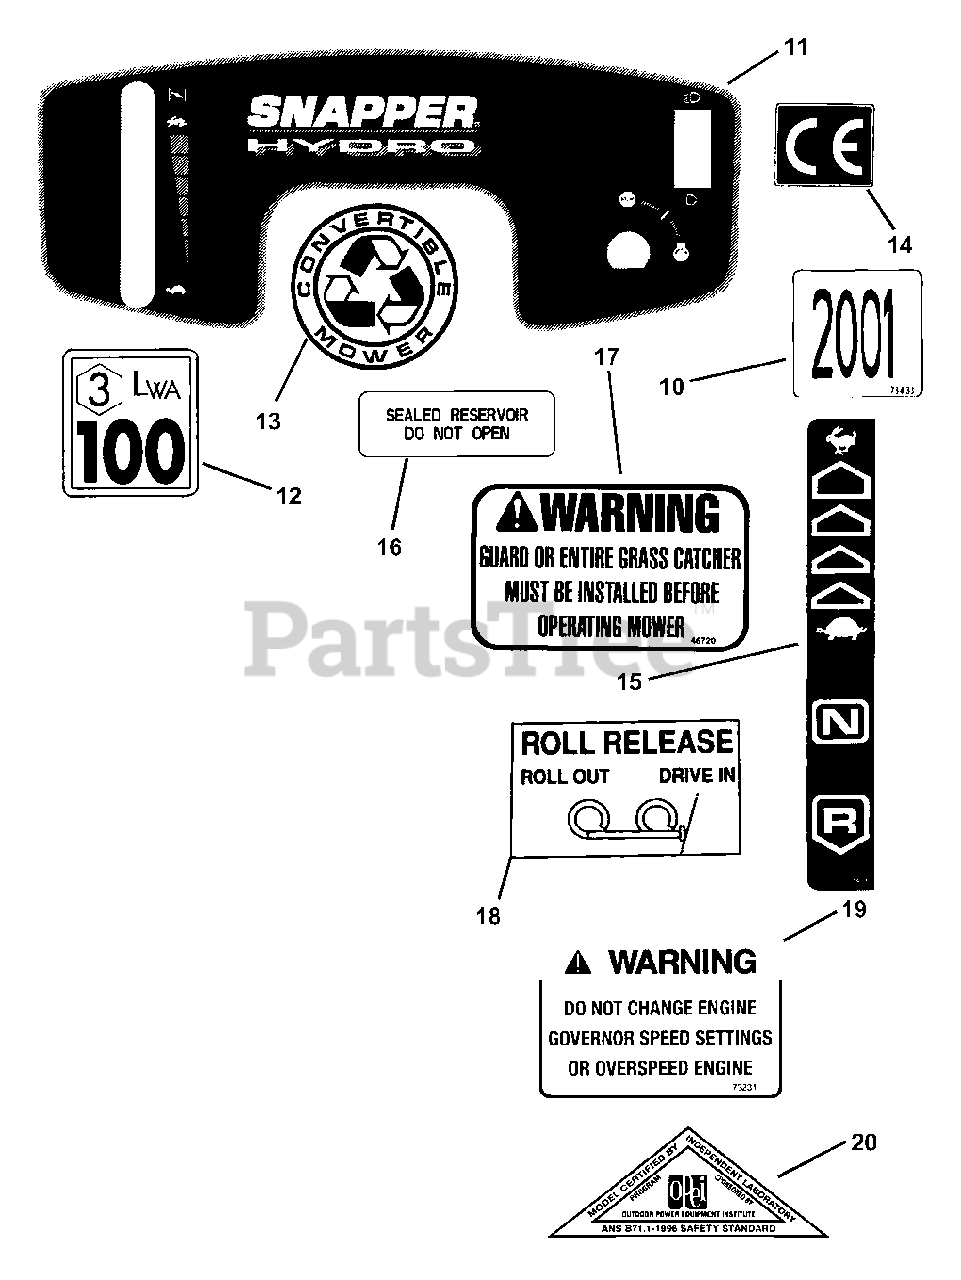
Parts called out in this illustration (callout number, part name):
10	DECAL, 2001 Year of Manufacture
11	DECAL, Console, Basic
11	DECAL, Console (2001 Model Year)
12	DECAL, Noise Control, Euro
13	LOGO, Convert- Blue/Silver
14	DECAL, European Community
15	DECAL, Shift Cover
16	DECAL, Hydro Reservoir
17	DECAL, Chute/Deflector
18	DECAL, Roll Release
19	DECAL, Warning Speed Setting
19	DECAL (German Version of Above)
19	DECAL, Dutch Version of Above)
19	DECAL, (Spanish Version of Above)
19	DECAL (Italian Version of Above)
19	DECAL (French Version of Above)
20	DECAL, OPEI
